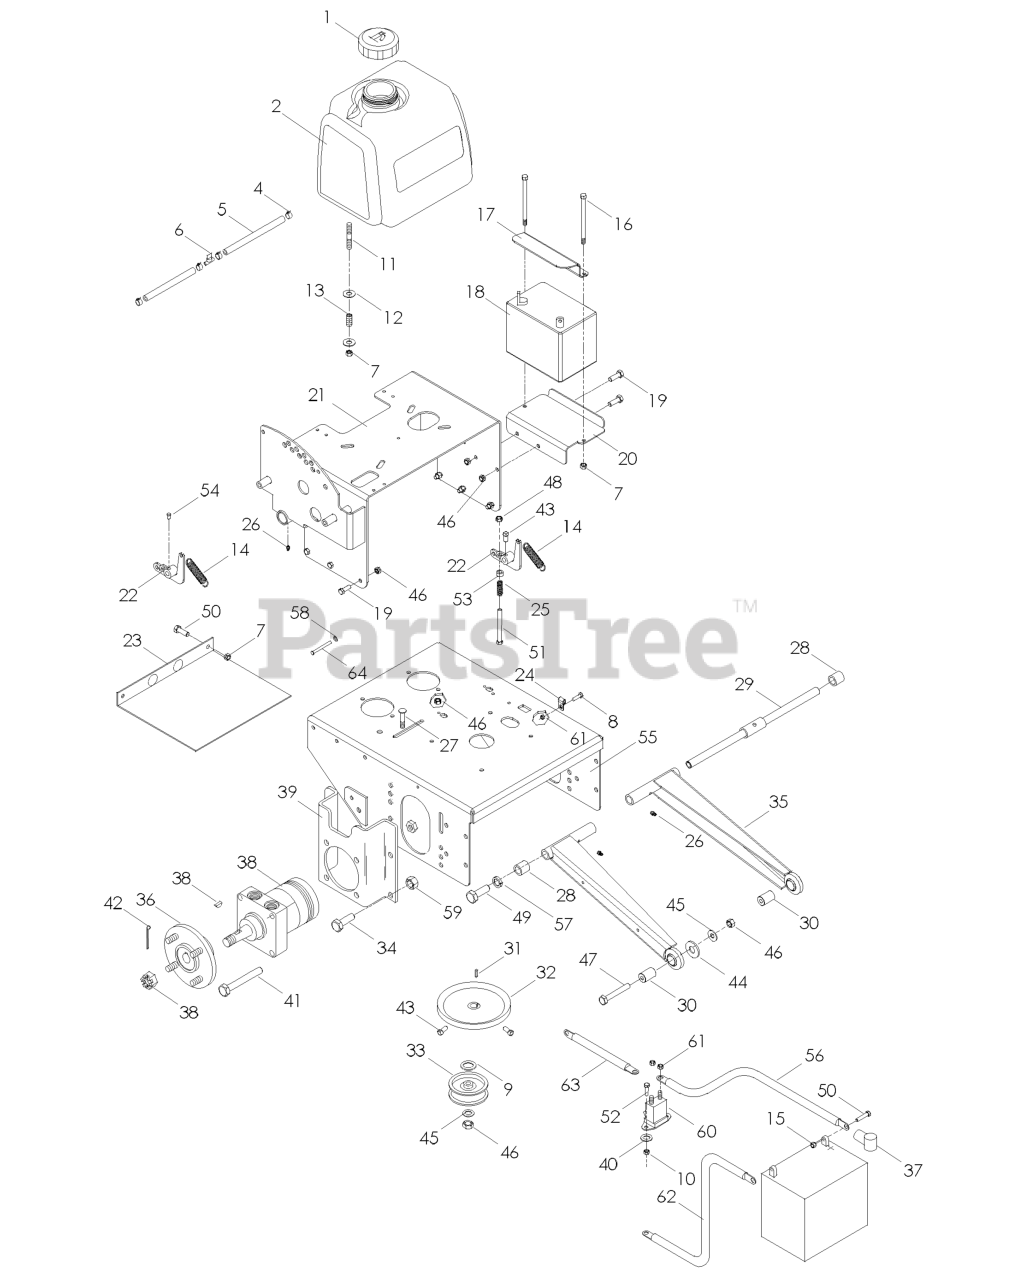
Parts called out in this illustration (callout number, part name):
1	FUEL CAP ANTI-SPLASH
3	JAM NUT 1/4C (2 2 PW01)
4	HOSE CLAMP
5	GAS LINE 10"
6	FUEL VALVE
7	NUT 5/16 NYLOC
8	HCS 1/4C X 3/4 HCS
9	WASHER, 3/8 SPEC
10	NUT 1/4C CENTER LOCK
11	STUD, 5/16C
12	WASHER 5/16 FLAT
14	SPRING-TRANS
15	NUT 5/16C CENTERLOCK
16	BOLT - 5/16 X 7
17	BATTERY STRAP
18	BATTERY, 12 V 330 AMP
19	SCREW 3/8C X 3/4 HEX CAP
20	BATTERY TRAY
21	TANK SUPPORT
22	PUMP ARM WELDMENT
23	LOWER BELT SHIELD
24	DOUBLE TUBE CLAMP
26	ZERK
27	RHSNB 3/8C X 2
29	STRUT SHAFT
30	FRONT SPACER
31	KEY 5 MM SQ X 25 MM
33	IDLER PULLEY
34	HCS 1/2C X 1 1/4 SERRATED HEAD
35	STRUT WELDMENT
36	HUB.WHEEL.ZTR
38	WHEEL MOTOR
39	MOTOR MOUNT
40	WASHER 1/4 INT TOOTH
41	HCS 1/2C X 2 3/4
42	COTTER PIN
43	SCREW 5/16C X 5/8 SQ HEAD
44	WASHER 1/2 FLAT
45	WASHER 3/8 FLAT
46	NUT 3/8C CENTERBLOCK
47	HCS 3/8C X 2 1/4
48	NUT 3/8-16 NYLOC
49	HHCS 1/2-13 X 1
50	HCS 5/16C X 3/4
51	HEX SCREW 3/8-20 X 2.75
52	HCS 1/4C X 5/8
54	5/16C X 5/8 "V" POINT
56	CABLE POSITIVE, LONG
57	WASHER 1/2" SPLIT LOCK
58	NUT PUSH
59	NUT 1/2-13 HEX NYLOC ZD
61	NUT.1/4-20.HEX.NYLOC.ZD
62	CABLE-NEGATIVE
63	CABLE POSITIVE, LONG
64	CLEVIS PIN
